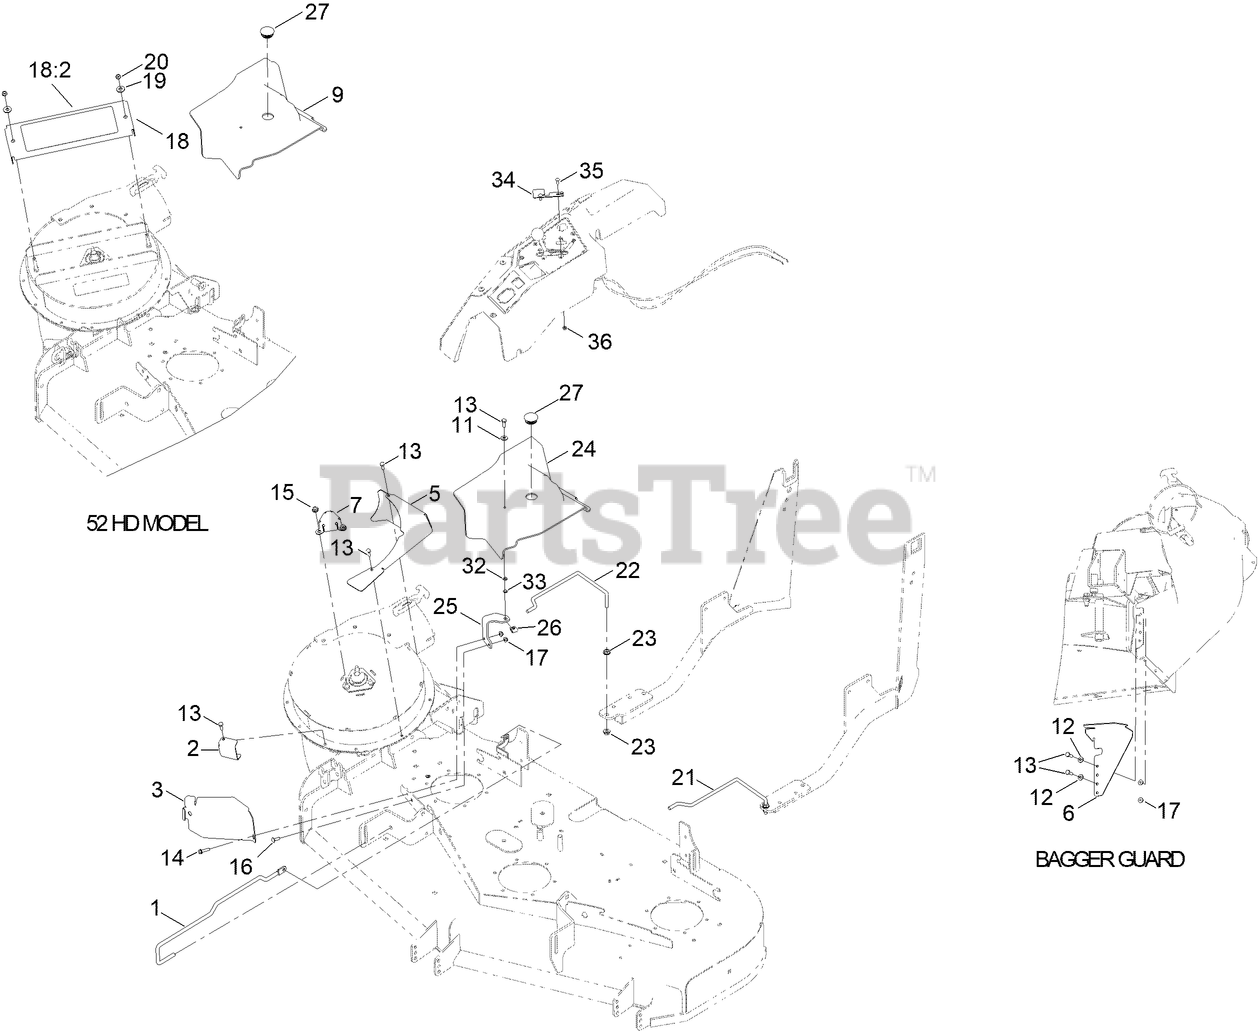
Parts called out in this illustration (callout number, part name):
1	ROD-SUPPORT, LOWER
2	GUARD-FRONT, LEFT
3	GUARD-BAGGER
5	GUARD-TOP
6	GUARD-BAGGER
7	COVER-NUT
9	BELT-COVER
11	WASHER-FLAT
12	WASHER-FLAT
13	SCREW-HH
14	SCREW-HHF
15	NUT-HF
16	BOLT-CARR
17	NUT-HF
18	COVER-BEARING
18:2	DECAL-DANGER
19	WASHER-FLAT
20	NUT-LOCK, NI
21	ROD-SUPPORT, REAR (LH)
22	ROD-SUPPORT, REAR (RH)
23	NUT-HHF, WHIZ
24	BELT COVER
25	BRACKET-COVER, BELT
26	NUT-SPEED
27	PLUG-PLASTIC
32	WASHER-FLAT
33	NUT-RETAINER
